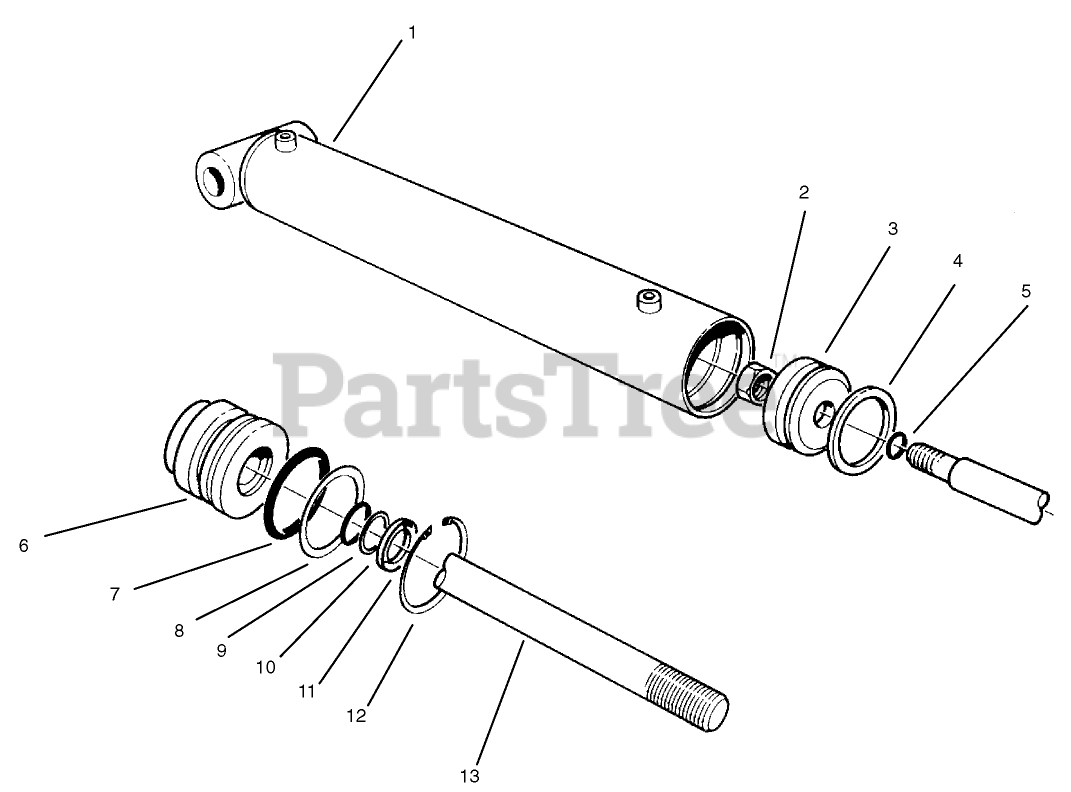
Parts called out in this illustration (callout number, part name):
1	Barrel
2	LOCKNUT
3	PISTON
4	Uniring
5	"O"Ring
7	"O"Ring
8	Washer-Backup
9	"O"Ring
10	Washer-Backup
11	Seal-Dust
12	RING-RETAINING
13	SHAFT
